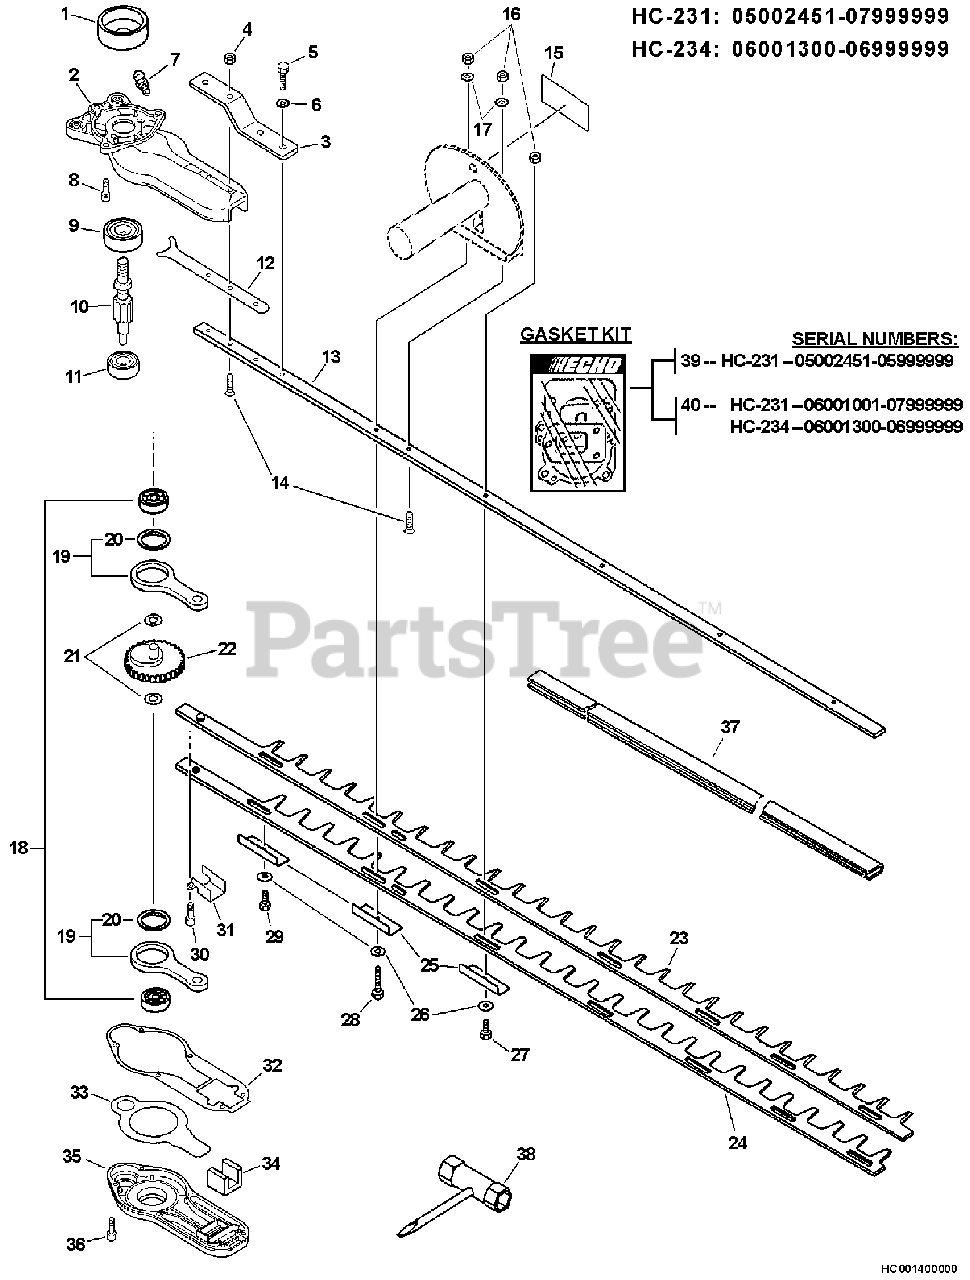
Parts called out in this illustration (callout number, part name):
1	DRUM, CLUTCH
2	CASE, GEAR - UPPER
3	BRACKET, ANGLE
4	NUT - 6 -- FLANGE
5	SCREW - 6X12
6	WASHER - 6
7	FITTING, GREASE
8	SCREW - 6X18
9	BEARING, BALL - 6200
10	GEAR - SPUR
11	BEARING, BALL - 608ZZ
13	SUPPORT, BLADE - 40" (101cm)
14	SCREW - 6X30
15	LABEL - CAUTION
16	LOCKNUT - 6
17	WASHER - 6
18	BEARING, BALL - 6200
19	ROD, CONNECTING
20	BEARING, NEEDLE
21	WASHER - 10
22	GEAR - SPUR
23	BLADE - 40" (101cm) -- UPPER
24	BLADE - 40" (101cm) -- LOWER
25	INSULATOR
29	BOLT - 6X35
30	SCREW - 4X16
31	GUIDE, BLADE
32	GASKET, GEAR CASE
33	PLATE, GEAR CASE
35	CASE, GEAR - LOWER
36	SCREW - 4X16
37	COVER, BLADE
38	T-WRENCH - 13X19mm
39	GASKET KIT
40	GASKET KIT
